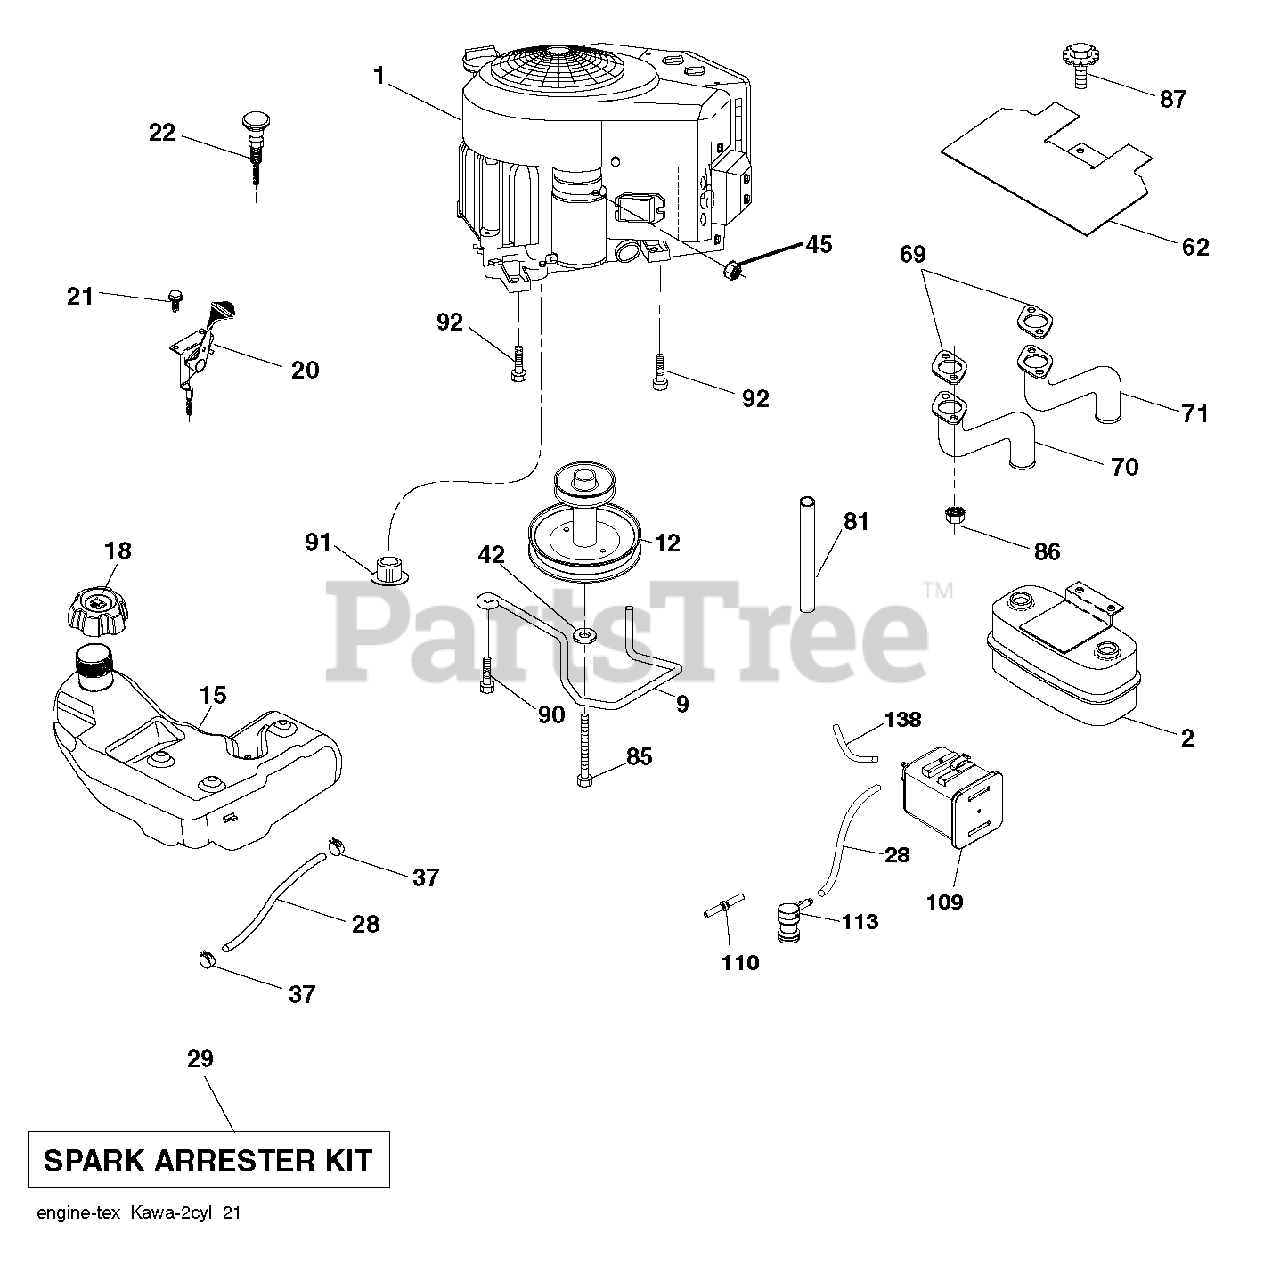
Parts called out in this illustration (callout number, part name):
2	MUFFLER.ASM.TWN.EXTNDED.DFLCTR
9	KEEPER.BELT.ENGINE.4.2
12	PULLEY ENGINE
18	CAP.ASM.FL.RITCH.3"E10.SYM.498
20	CONTROL.THROTTLE.COBRA.BLACK
21	SCREW.#10 X 0.750.BOS
22	CONTROL, CHOKE
28	LINE.FUEL.64"REAR.EMIS
29	KIT.SPARK ARRESTOR 794945 B&S
37	HOSE CLAMP
42	LOCKWASHER
45	NUT
62	SHIELD.HEAT.MUFFLER
70	TUBE.EXHAUST.LH.FR961/FR730
71	TUBE.EXHAUST.RH.FR961/FR730
81	TUBE, DRAIN OIL ASM.
85	BOLT HEX 7/16-20X4-1/4"
86	NUT.HEX.FLANGE.TOPLOCK
87	Bolt, 5/16-18 X 1-3/4
90	SCREW 3/8-16X1
91	BUSHING.1.375OD
92	SCREW 3/8-16X1
109	CANNISTER, CARBON
110	VALVE.ASM.ANTI-SLOSH
113	VALVE.SLANT.CARTRDG.90 DEG.TEX
138	PURGE.LINE.36"REAR.CALIFORNIA
